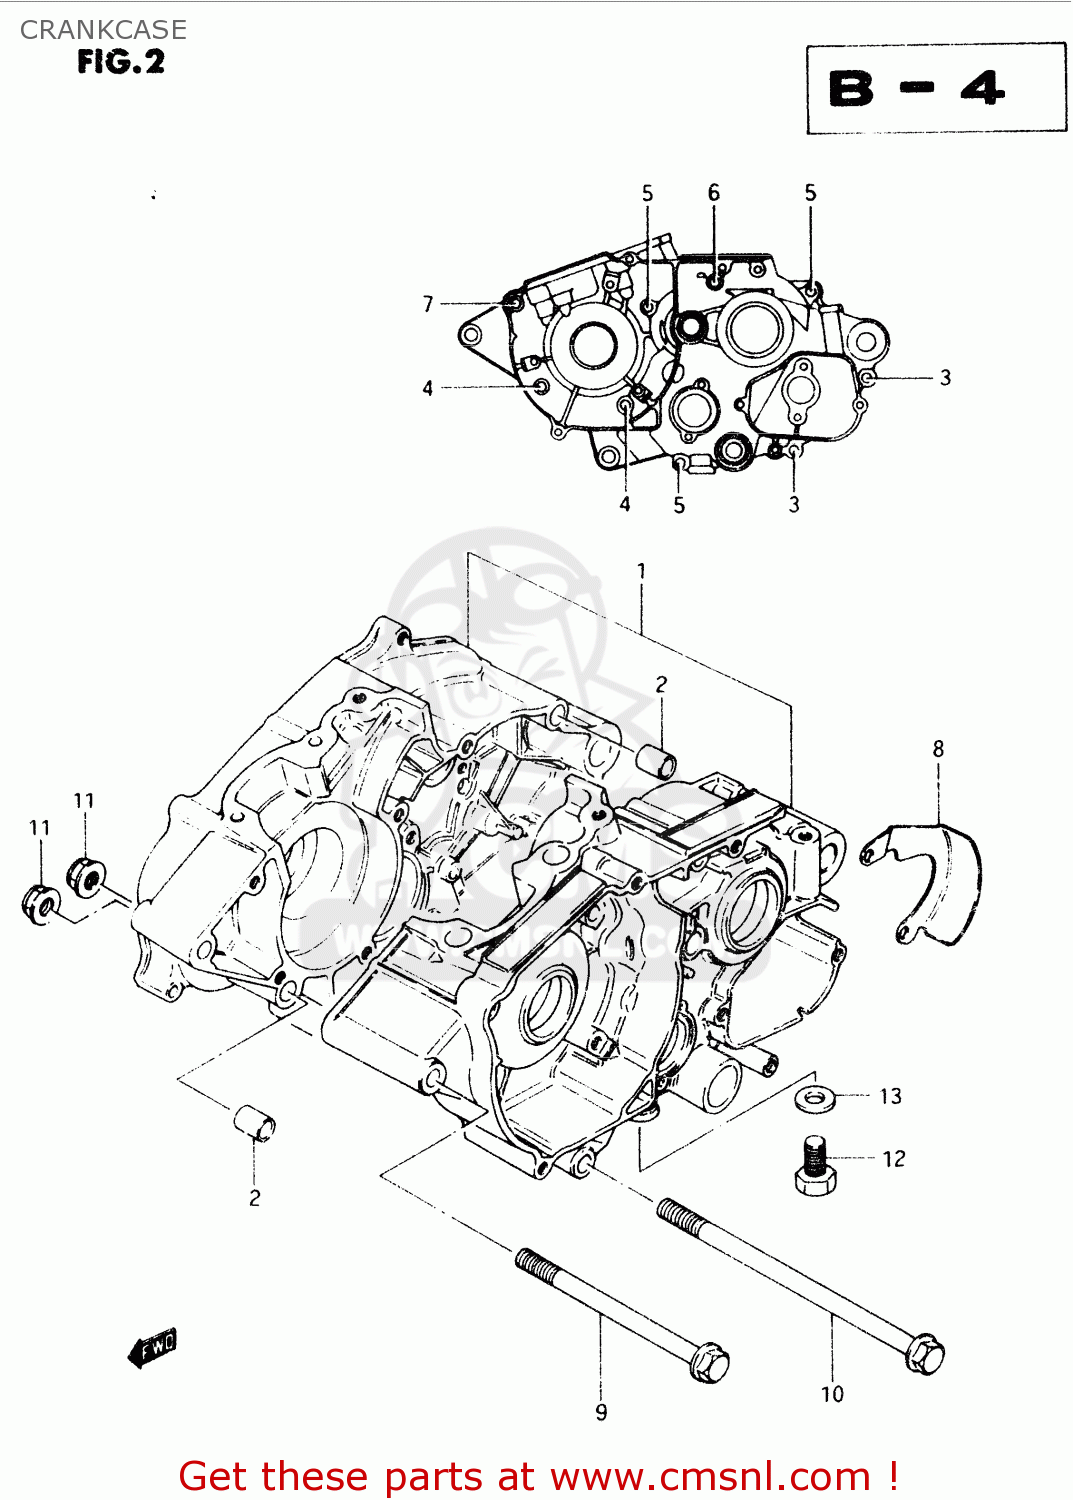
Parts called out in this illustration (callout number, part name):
1	CRANKCASE SET
2	PIN
3	SCREW 6X30
4	SCREW
5	SCREW
6	SCREW
7	SCREW
8	PLATE,OIL HOSE
9	BOLT(8X120)
10	BOLT(8X160)
11	NUT
12	BOLT
13	GASKET(10X14X3.6) (NAS)
